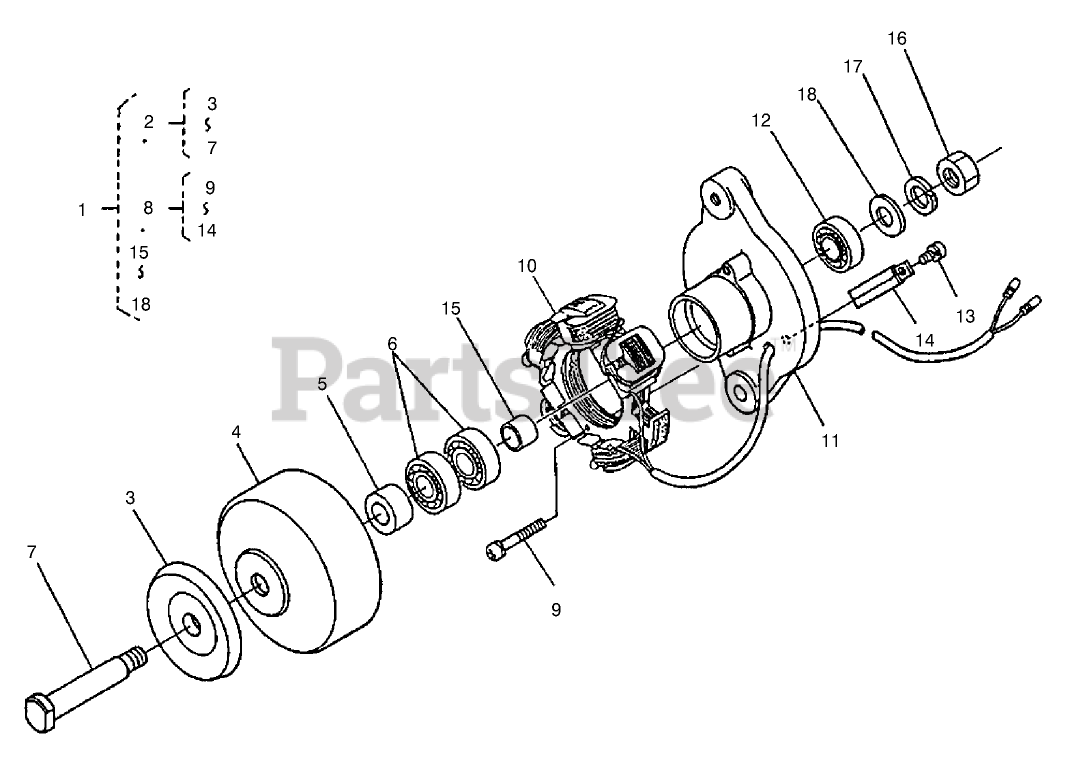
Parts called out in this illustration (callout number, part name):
1	DYNAMO ASM
2	ROTOR ASM
3	PULLEY
5	COLLAR
6	BEARING-BALL
7	SHAFT-FAN
8	STATOR ASM
9	SCREW-HEAD, ROUND
10	STATOR
12	BEARING-BALL
13	SCREW-HEAD, ROUND
14	CLAMP-CORD
15	COLLAR
17	WASHER-SPRING
18	WASHER-PLAIN
